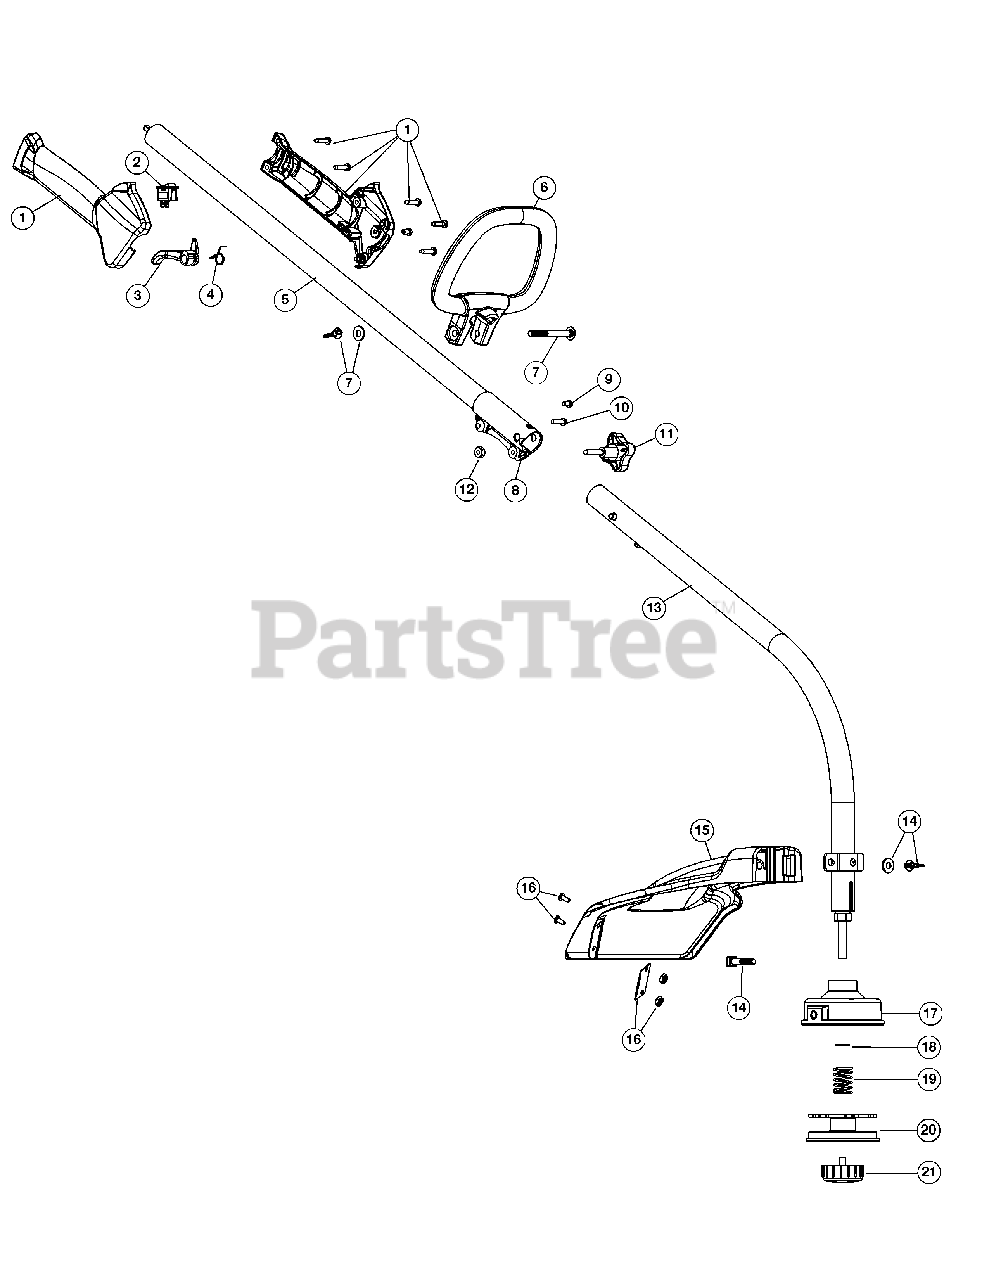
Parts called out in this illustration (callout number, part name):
1	Throttle Housing Assembly (Incl. 2-4)
3	Throttle Trigger
4	Throttle Trigger Spring
5	Upper Shaft Housing Assembly
6	D-Handle (Incl. 7)
7	D-Handle Hardware Assembly
8	Split Boom Coupler (Incl. 9-12)
9	Anti-Rotation Screw
11	Adjustment Knob
12	Knob Retainer Nut
13	Lower Shaft Housing Assembly
14	Shield Mounting Hardware
15	Shield Assembly (Incl. 16)
16	Blade Assembly
17	Outer Spool Assembly (Incl. 18)
20	Inner Reel
21	Bump Head Knob Assembly
